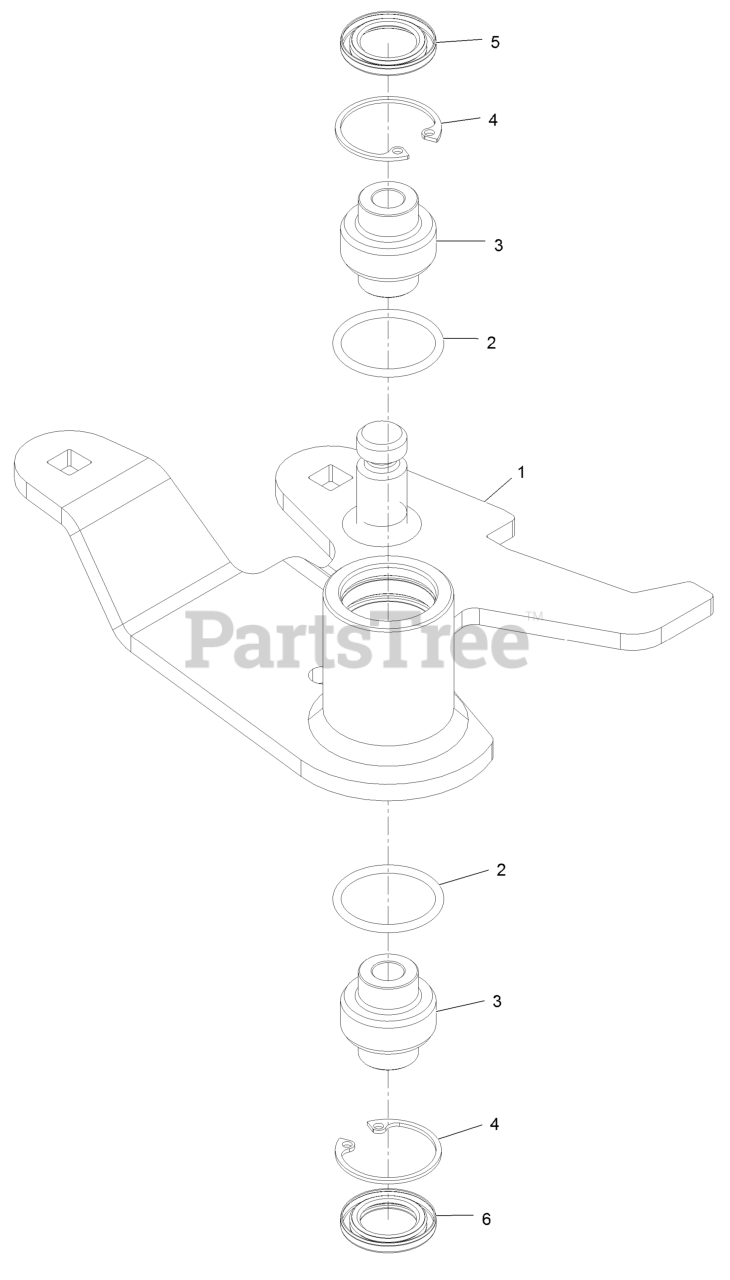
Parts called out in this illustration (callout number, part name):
1	ASM-Idler Arm, 96Rd [red]
3	Bearing-Spherical
4	Ring-Snap
5	Seal-Lip, Single
6	Seal-Lip, Double
